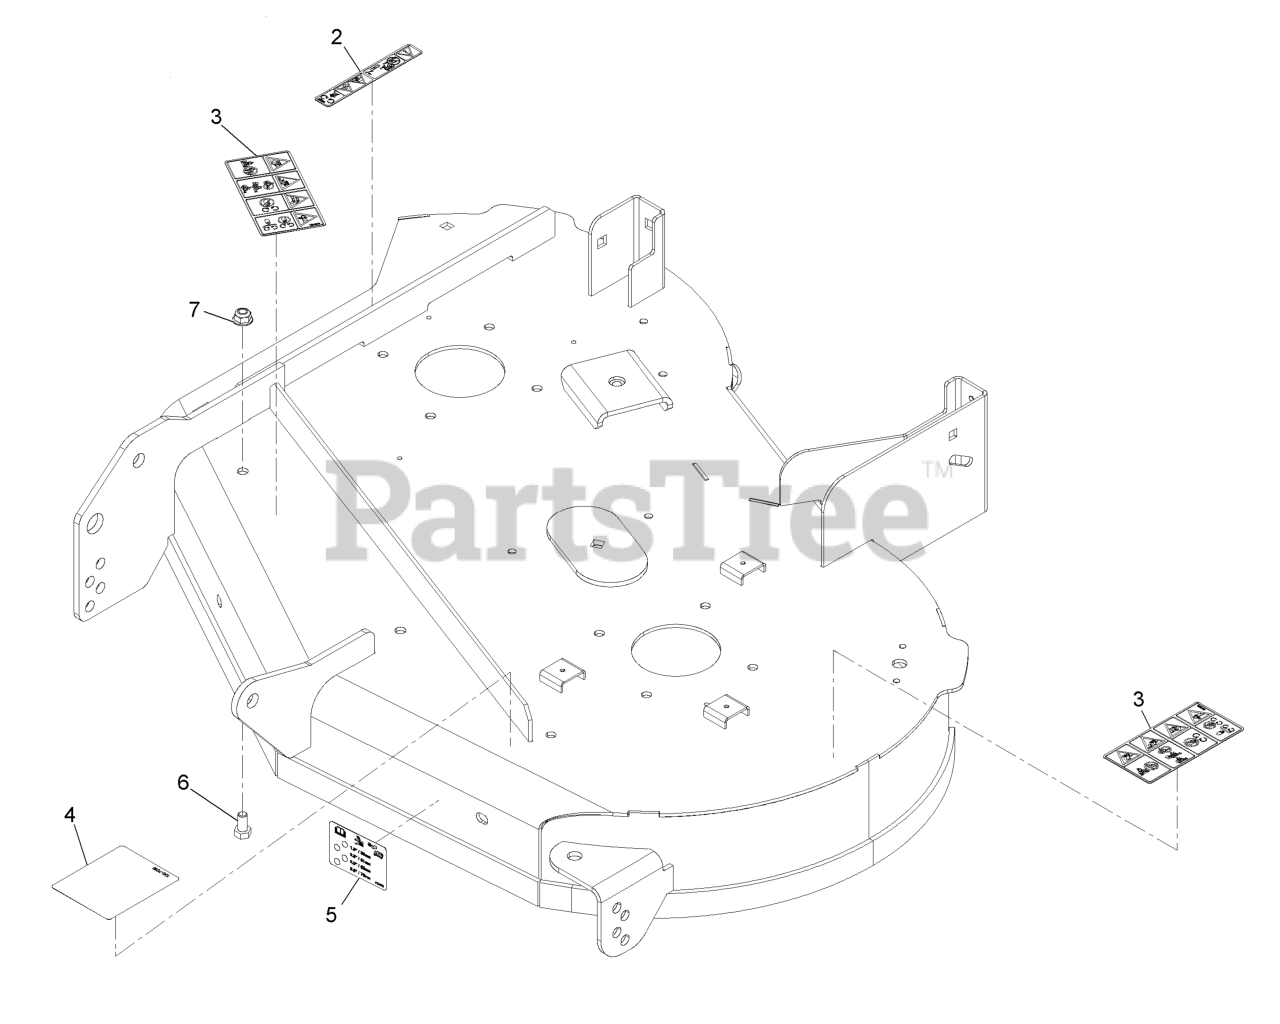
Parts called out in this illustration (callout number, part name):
2	DECAL-DANGER
3	DECAL-DANGER, DECK
4	DECAL-ROUTING, BELT
5	DECAL-SCALP, ANTI
6	SCREW-HH
7	NUT-HF, NI
